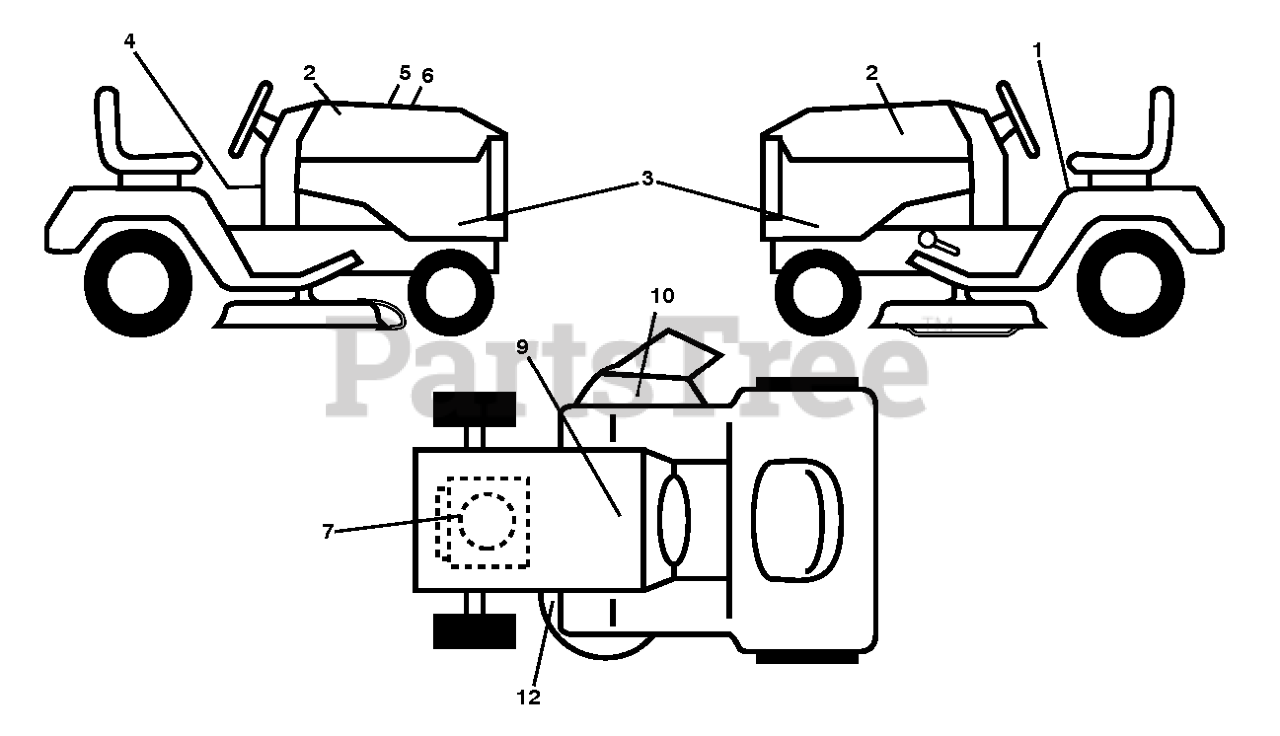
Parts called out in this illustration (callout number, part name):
1	DECAL.FENDER.WARNING.ENGLISH
2	DECAL.BADGE.170MM.TEXTLOGO.
3	DECAL.SIDE.PANEL.YTH22V46.2013
4	DECAL, WARNING SPARK ARRESTOR
5	DECAL.WARNING.CUST.RESP.E85.
6	DECAL.RPL.BSM.44.INTK.TLW.46
7	DECAL.ENG.BS.22HP.INTK
8	DECAL.MOWER.WARN.KEEP.HAND.AWY
9	DECAL BTRY SYMBOLS
12	DECAL.V-BELT.SCH.42/46"MEC/ELE
